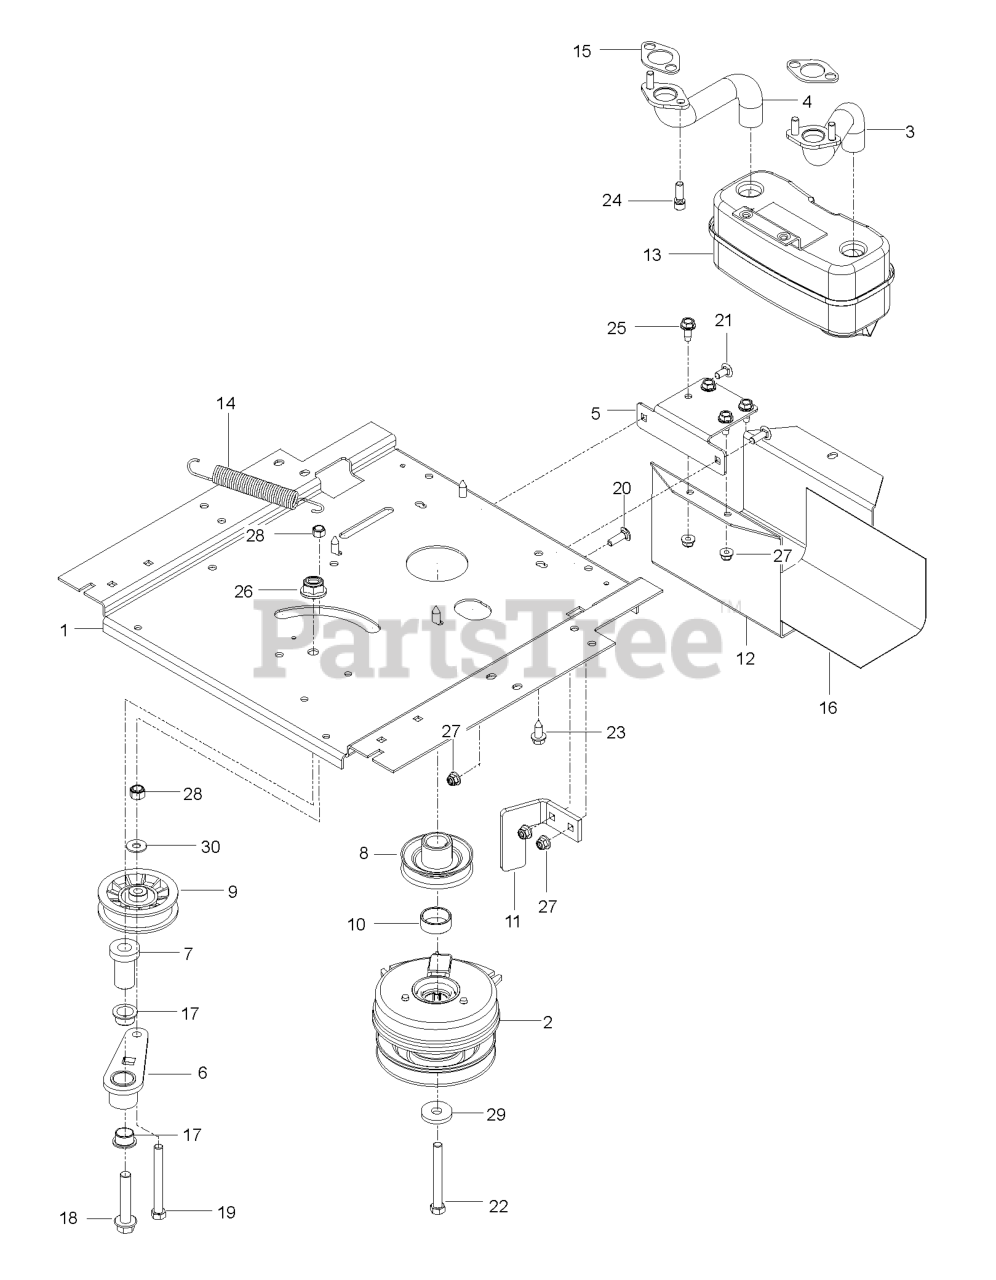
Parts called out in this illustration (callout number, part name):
1	PLATE.ENGINE.PNT.23"FRAME.EDIP
2	CLUTCH.105.FT-LBS
3	EXHAUST.TUBE.LH.BS/TWIN
4	EXHAUST.TUBE.RH.B&S.TWIN.INTEK
5	BRACKET MUFFLER MS431BLK
6	ARM IDLER
7	SPINDLE.IDLER
8	PULLEY.ENGINE
9	PULLEY, IDLER
10	T & B SPACER
11	STOP, CLUTCH, BLACK
12	GUARD.MUFFLER.WO.TOW.HITCHX431
13	MUFFLER ASM TWIN
14	SPRING, DECK DRIVE
15	GASKET.MUFFLER
16	HEAT SHIELD
17	BEARING.FLANGED.PLASTIC.3/4ID
18	BOLT.FLANGE.1/2-13 X 2.75.GRD5
19	HCS 3/8-16X3-1/2 TAPBLT GR5 ZD
20	Bolt, Carriage 5/16-18 UNC x 1 (AYP part number)
21	Bolt, Carriage 5/16-18 x 3/4 Gr. 5
22	CLUTCH BOLT7/16-20X3.5 GR524HR
23	SCREW 3/8-16X1
24	SCREW.SOCKET.HEAD.5/16-18
25	Screw, Hex Washer Head, Threaded, Rolling 5/16-18 x 3/4 Type TT
26	NUT, 1/2-13 HEX FLG NYLOC ZD
27	5/16-18 NYLOC FLANGE NUT
28	NUT 3/8-16 NYLOC
29	Washer 1 - 1/2 OD x 15/32 ID x .250 (AYP part number)
30	WASHER 5/16 FLAT
